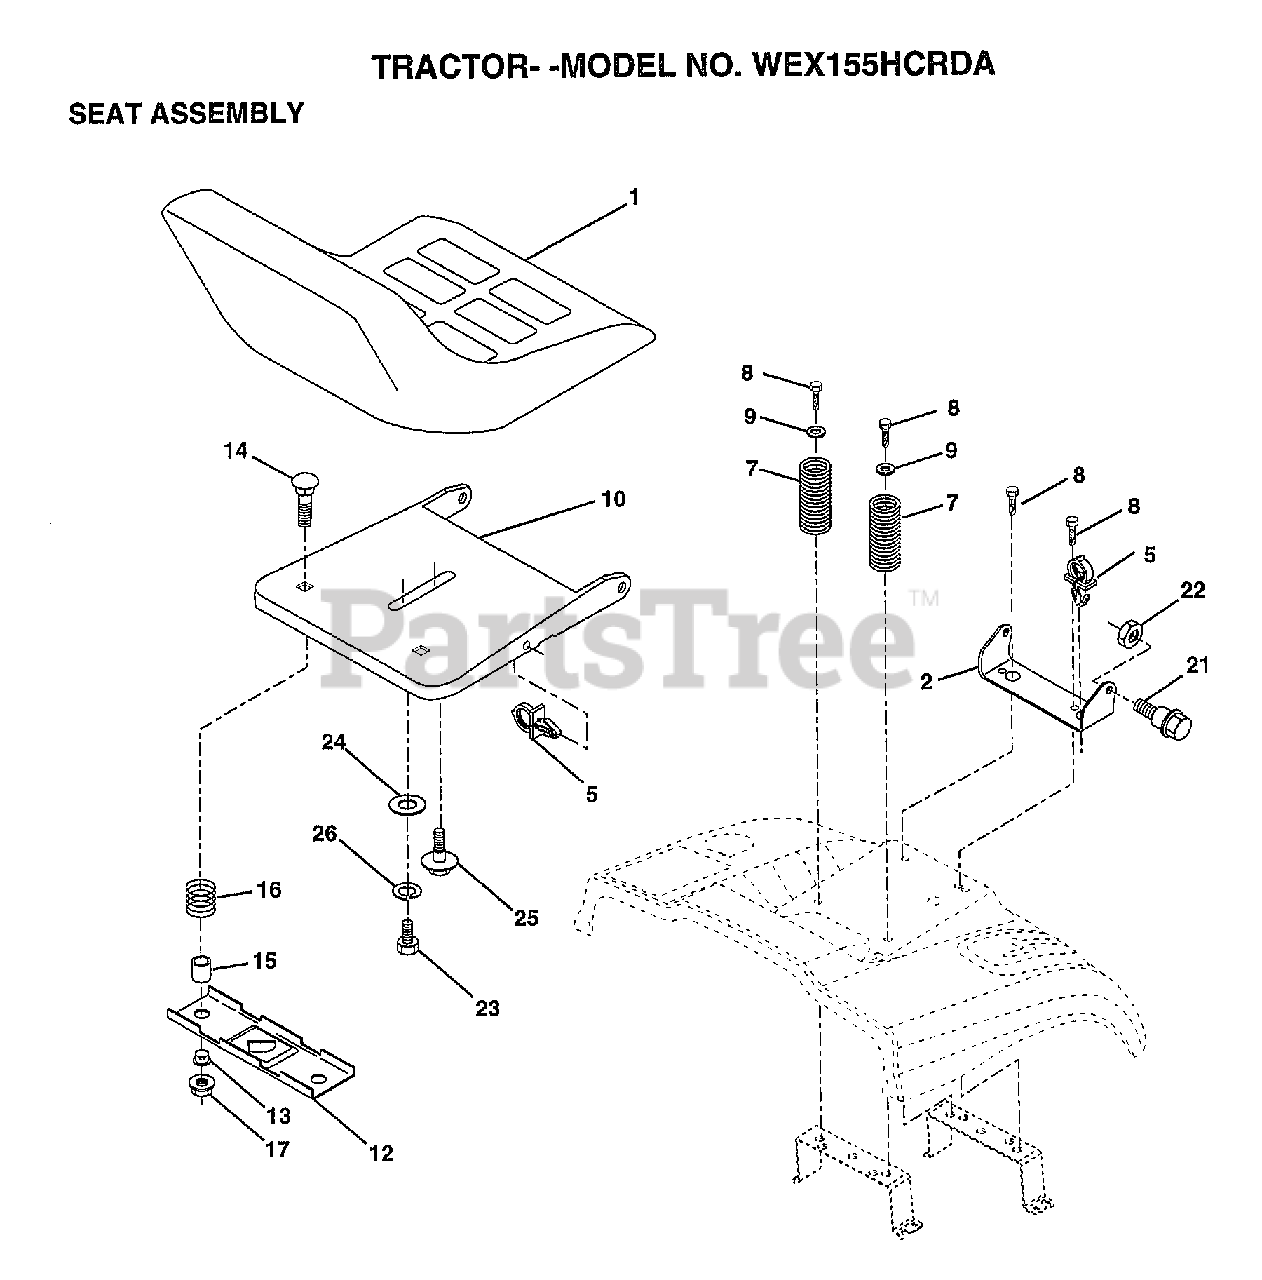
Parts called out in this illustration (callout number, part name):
2	BRACKET PVT SEAT
5	CLIP.PUSH-IN.HING
7	SPRING COMPRESSIO
8	SCREW GTV
9	WASHER
10	PAN-SEAT
12	BRKT SWITCH
13	BUSHING
14	BOLT-RD HD SQ NK
15	SPACER SPLIT
16	SPRING COMPRESSED
21	"BOLT,SHOULDER"
22	NUT
23	BOLT
24	WASHER
25	"BOLT,SHOULDER"
26	LOCKWASHER
